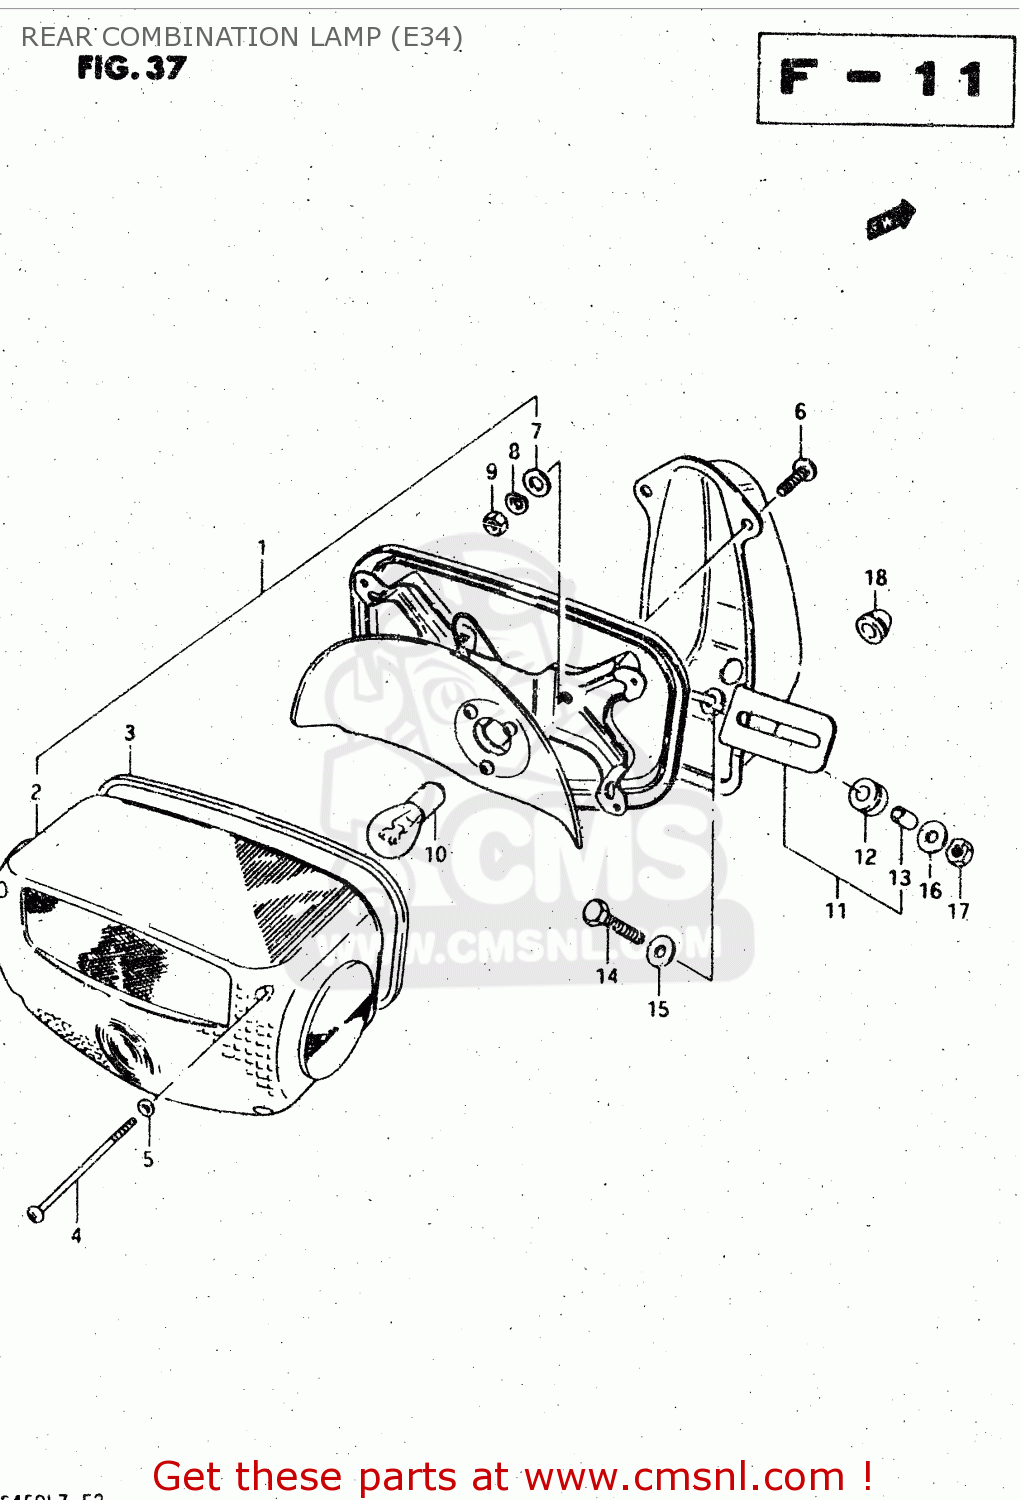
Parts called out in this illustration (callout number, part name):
1	LAMP UNIT, TAIL
2	LENS
3	GASKET (NAS)
4	SCREW (4X55)
5	GASKET (NAS)
6	SCREW 6X12
7	WASHER
8	LOCK WASHER
9	NUT
10	BULB(12V21/5W)
11	BRACKET ASSY
12	CUSHION
13	SPACER
14	BOLT
15	WASHER (6.5X20X1.2)
16	WASHER
17	NUT
18	GROMMET
